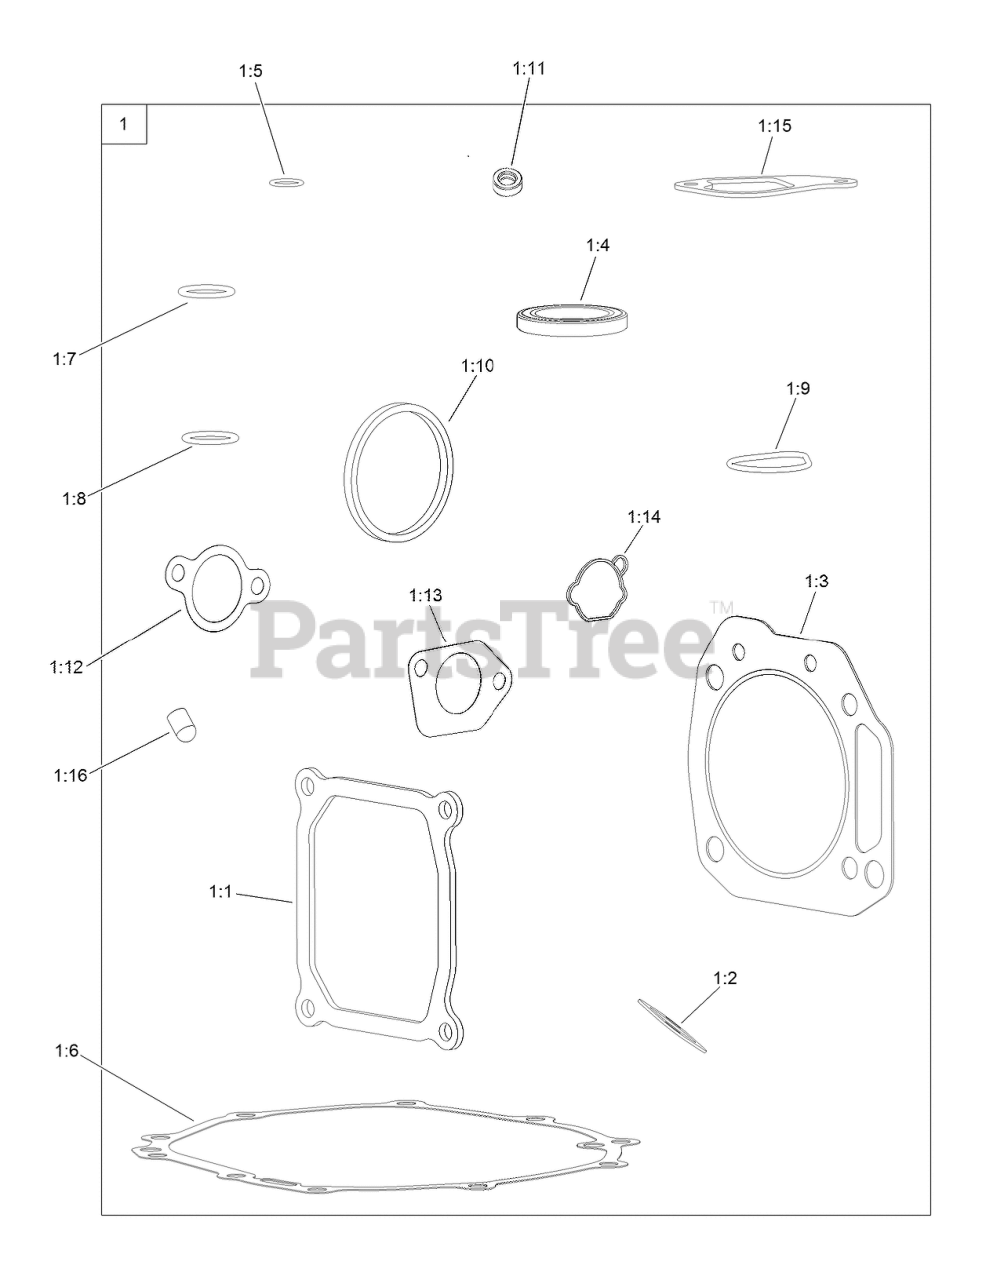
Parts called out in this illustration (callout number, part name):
1	GASKET AND SEAL KIT
1:1	GASKET-COVER, VALVE
1:2	GASKET-EXHAUST
1:3	GASKET-CYCLINDER
1:4	SEAL-OIL
1:5	O-RING
1:6	GASKET-CRANKCASE
1:7	O-RING
1:8	O-RING
1:9	SEAL-PUMP, OIL
1:10	SEAL-ADAPTOR, OIL
1:11	SEAL-OIL
1:12	GASKET-CARBURETOR
1:13	GASKET-CARBURETOR
1:14	GASKET-CARBURETOR
1:15	GASKET-BREATHER
1:16	CAP-SEAL
